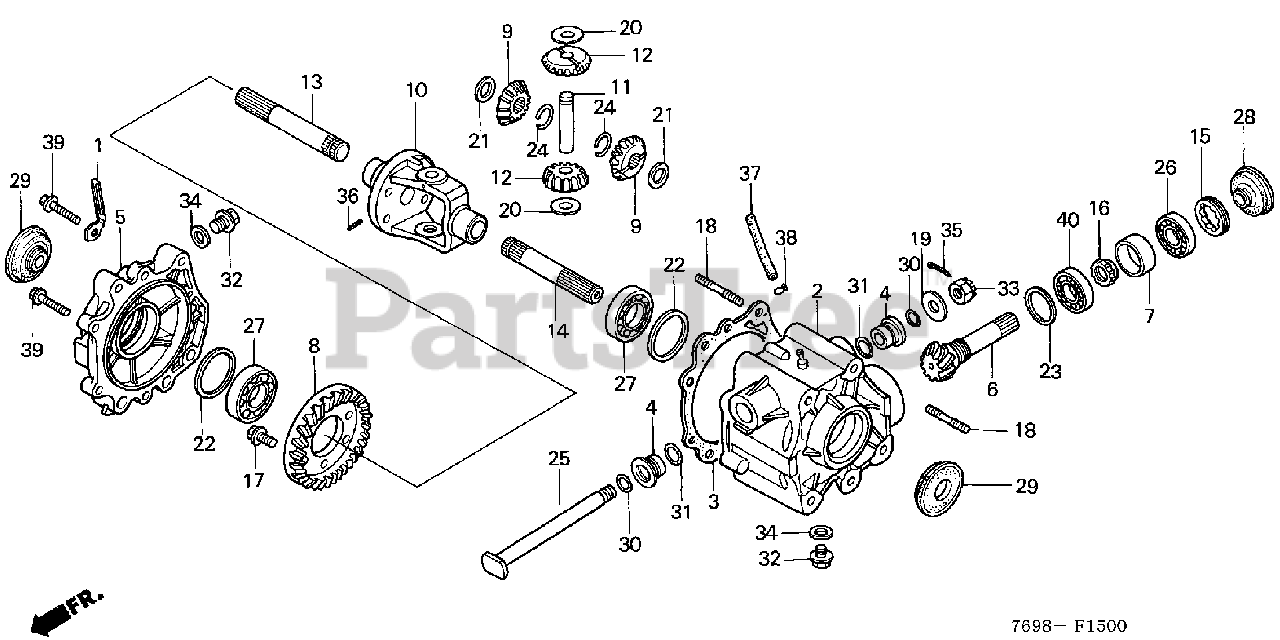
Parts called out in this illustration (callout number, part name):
1	CLIP A, WIRE HARNESS
2	HOUSING, FR. DIFFERENTIAL
3	GASKET, FR. DIFFERENTIAL HOUSING
4	BUSH, CENTER PIN
5	COVER, FR. DIFFERENTIAL
6	SHAFT, FR. DIFFERENTIAL INPUT
7	COLLAR, FR. DIFFERENTIAL INPUT SHAFT
8	GEAR, FR. DIFFERENTIAL DRIVEN
9	GEAR, DIFFERENTIAL (16T)
10	CASE, FR. DIFFERENTIAL
11	SHAFT, DIFFERENTIAL PINION
12	PINION, DIFFERENTIAL (16T)
13	SHAFT, R. FR. DRIVE
14	DRIVESHAFT, L. FR.
15	NUT, LOCK (55MM)
16	NUT, LOCK (25MM)
17	BOLT, HEX. (10MM)
18	BOLT, STUD (10X45)
19	WASHER, THRUST (14X30X2.5)
20	WASHER A, DIFFERENTIAL PINION (16.2X30X0.7)
20	WASHER B, DIFFERENTIAL PINION (16.2X30X0.8)
20	WASHER C, DIFFERENTIAL PINION (16.2X30X0.9)
20	WASHER D, DIFFERENTIAL PINION (16.2X30X1.0)
21	WASHER, DIFFERENTIAL GEAR
22	SHIM, FR. DIFFERENTIAL CASE (54X64.5X1.8) (L)
22	SHIM, FR. DIFFERENTIAL CASE (54X64.5X1.85) (M)
22	SHIM, FR. DIFFERENTIAL CASE (54X64.5X1.9) (N)
22	SHIM, FR. DIFFERENTIAL CASE (54X64.5X1.95) (O)
22	SHIM, FR. DIFFERENTIAL CASE (54X64.5X2.0) (P)
22	SHIM, FR. DIFFERENTIAL CASE (54X64.5X2.05) (Q)
22	SHIM, FR. DIFFERENTIAL CASE (54X64.5X1.5) (F)
22	SHIM, FR. DIFFERENTIAL CASE (54X64.5X1.55) (G)
22	SHIM, FR. DIFFERENTIAL CASE (54X64.5X1.6) (H)
22	SHIM, FR. DIFFERENTIAL CASE (54X64.5X1.65) (I)
22	SHIM, FR. DIFFERENTIAL CASE (54X64.5X1.7) (J)
22	SHIM, FR. DIFFERENTIAL CASE (54X64.5X1.75) (K)
23	SHIM, PINION (45.5X51.5X1.35) (A)
23	SHIM, PINION (45.5X51.5X1.4) (B)
23	SHIM, PINION (45.5X51.5X1.45) (C)
23	SHIM, PINION (45.5X51.5X1.5) (D)
23	SHIM, PINION (45.5X51.5X1.55) (E)
23	SHIM, PINION (45.5X51.5X1.6) (F)
23	SHIM, PINION (45.5X51.5X1.65) (G)
23	SHIM, PINION (45.5X51.5X1.25) (R)
23	SHIM, PINION (45.5X51.5X1.3) (S)
24	CIRCLIP (OUTER) (22MM)
25	PIN, CENTER
26	BEARING, RADIAL BALL (6304) (NACHI)
26	BEARING, SPECIAL (22) (KOYO)
27	BEARING, RADIAL BALL (62/32)
28	SEAL, WATER (33X58X12)
29	OIL SEAL (22X52X11.5)
30	O-RING (17.8X2.4) (SHOWA)
31	O-RING (23.5X2.6)
32	BOLT, DRAIN PLUG (14MM)
33	NUT, CASTLE (14MM)
34	WASHER, DRAIN PLUG (14MM)
35	PIN, COTTER (3.0X45)
36	PIN, SPRING (4X32)
37	BULK HOSE, FUEL (4.5X3000) (4.5X200)
38	CLIP, TUBE (B8)
39	BOLT, FLANGE (8X32)
40	BEARING, RADIAL BALL (6205)
